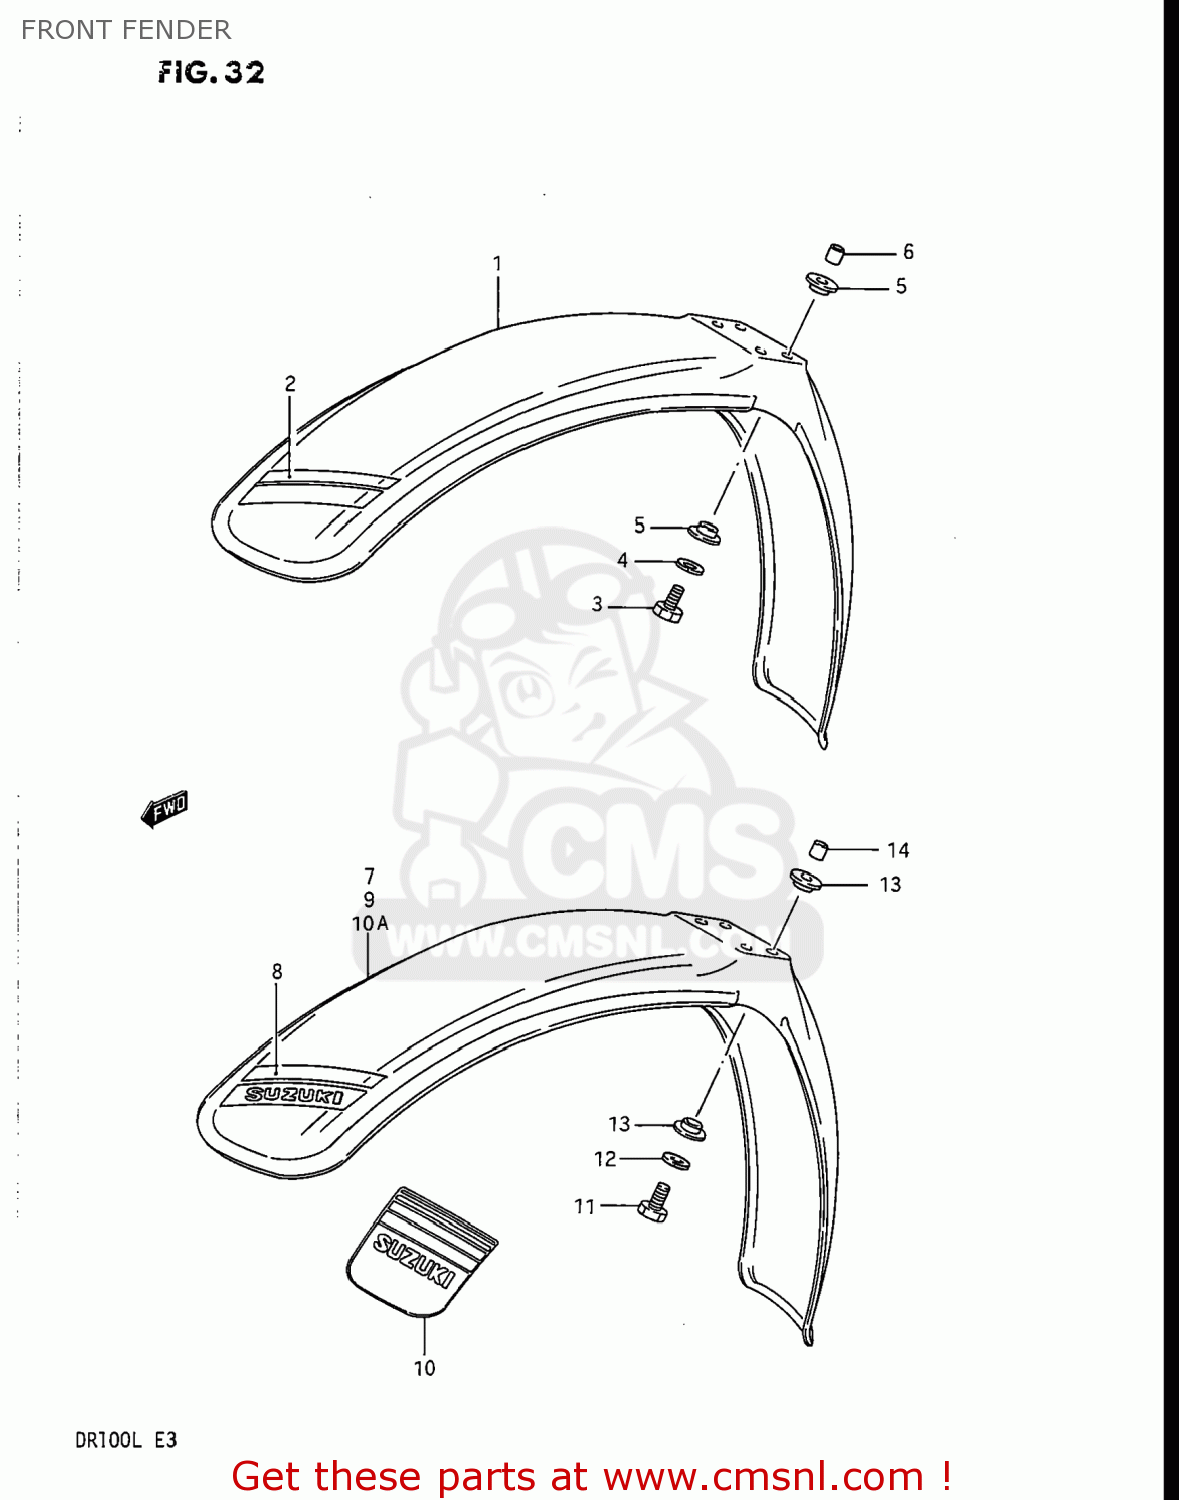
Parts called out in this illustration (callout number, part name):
1	FENDER,FRONT
2	TAPE SET,FRONT FENDER
3	BOLT
4	WASHER,LOCK
5	WASHER
6	SPACER (6.8X10X10)
7	FENDER COMP,FRONT
8	TAPE SET,FRONT FENDER
9	FENDER,FRONT
10	TAPE,FRONT FENDER
10A	FENDER,FRONT
11	BOLT
12	WASHER,LOCK
13	WASHER
14	SPACER (6.8X10X10)
